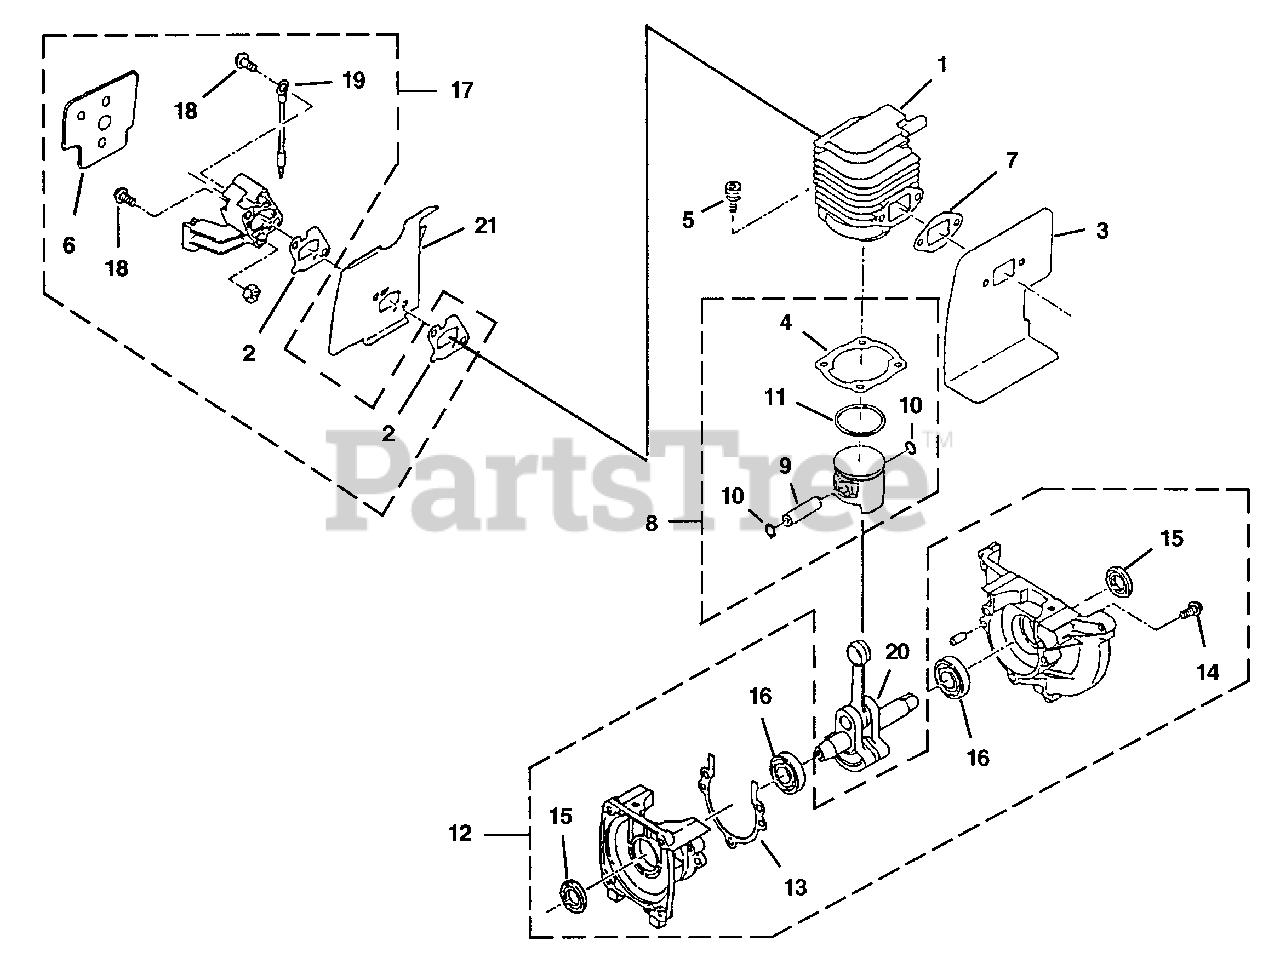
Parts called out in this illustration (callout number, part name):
1	CYLINDER ASSEMBLY
2	GASKET-Heat Dam
3	INSULATOR-Muffler
4	GASKET-Cylinder
5	SCREW-Socket HD (MS x 20 W SW)
6	INSULATOR-Gasket
6	INSULATOR-Carburetor
7	GASKET-Muffler
8	PISTON ASSEMBLY
9	PIN-Piston
10	RING-Retaining
11	RING-Piston
12	CRANKCASE ASSEMBLY
13	GASKET-Crankcase
14	SCREW (M5 x 25)
15	OIL SEAL
16	BALL BEARING
17	HEAT DAM ASSEMBLY
18	SCREW-Socket Hd (M5 x 25)
19	WIRE-Ground
20	CRANKSHAFT COMPLETE
21	INSULATOR - Carburetor
